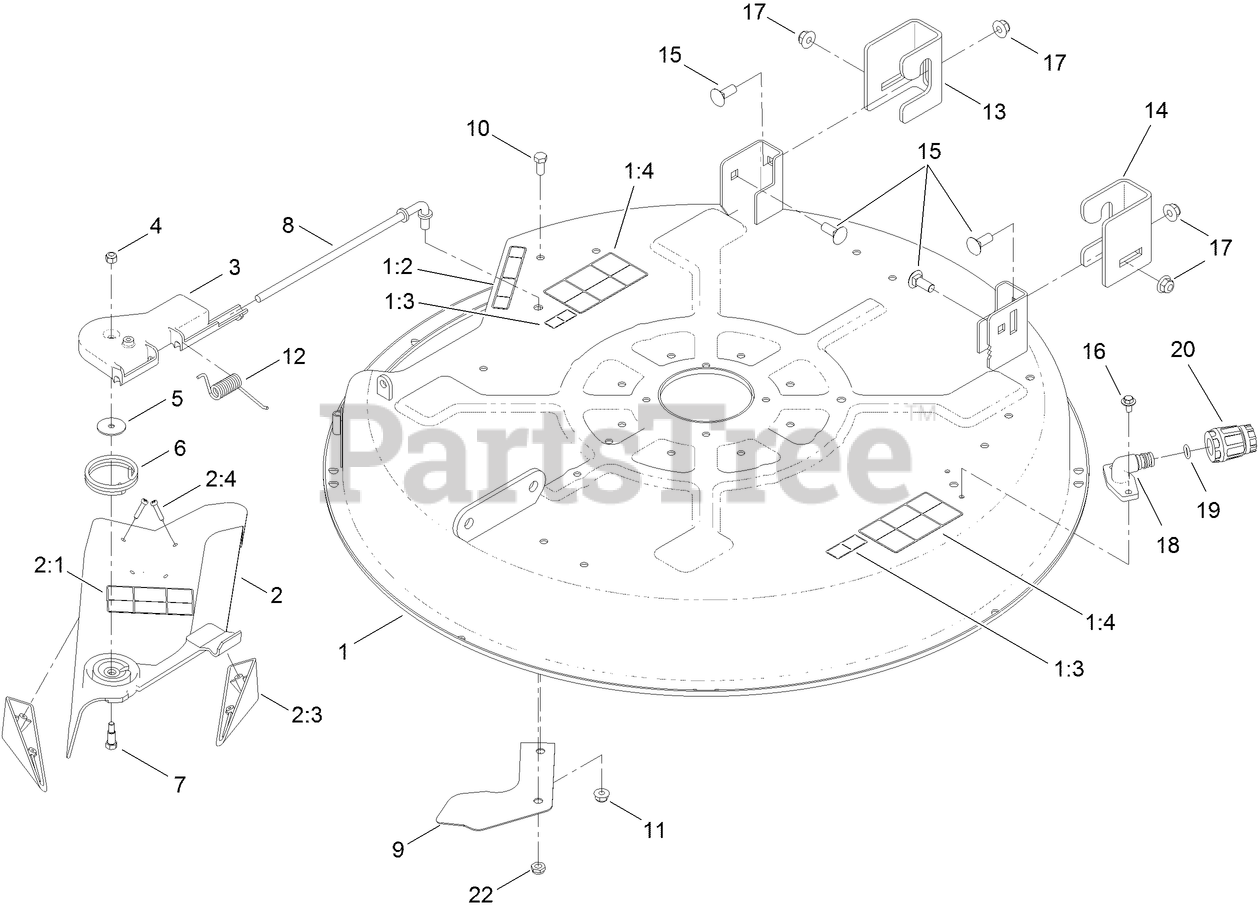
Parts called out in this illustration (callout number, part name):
1	32 INCH DECK AND DECAL ASM
1:2	DECAL-DANGER
1:3	DECAL-DANGER
1:4	DECAL-DANGER
2	32 INCH DEFLECTOR ASM
2:1	DECAL-DANGER
2:3	KICKER
2:4	SCREW-PPH
3	PIVOT-HINGE, DEFLECTOR
4	NUT-LOCK, NI
6	SPRING-TORSION
7	BOLT-SHOULDER
8	ROD-PIVOT
9	RAMP-DEFLECTOR
10	SCREW-HH
11	NUT-HF, NI
12	SPRING-TORSION
14	BRACKET-HANGER, LH
15	BOLT-CARR
16	SCREW-HHFTF
17	NUT-HF, NI
19	O-RING
20	CONNECTOR-HOSE
